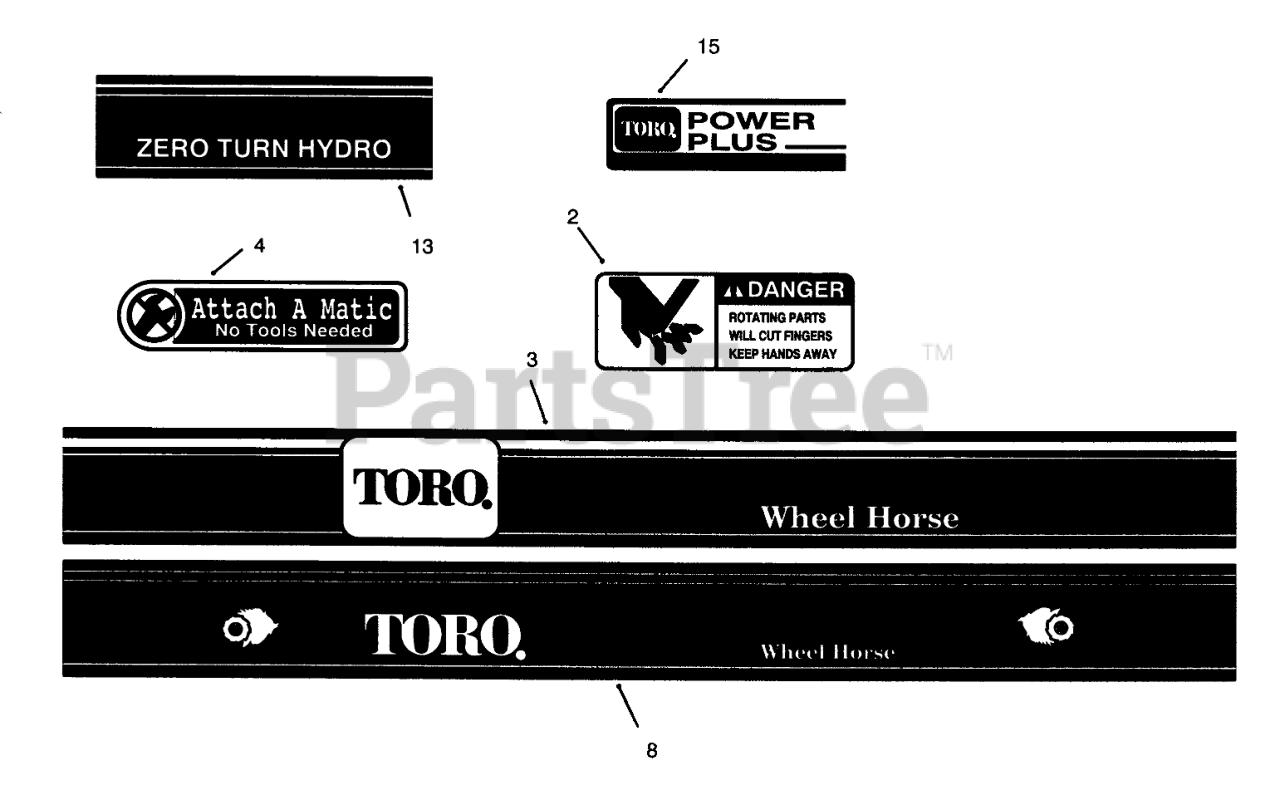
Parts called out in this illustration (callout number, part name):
2	DECAL-DANGER
3	DECAL-REAR 600
4	Decal-Attac-O-Matic
8	DECAL 616-Z
13	DECAL-ZERO TURN HYD
15	DECAL POWER PLUS 16
